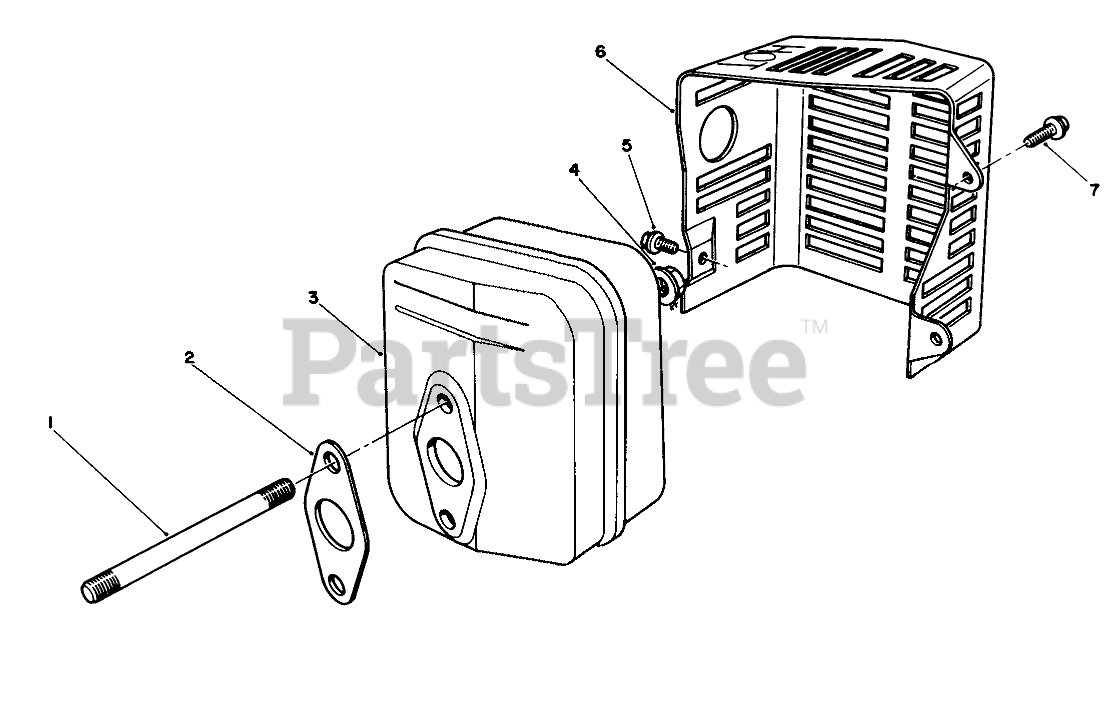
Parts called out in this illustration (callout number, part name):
2	GASKET
3	MUFFLER
5	SCREW
6	COVER
